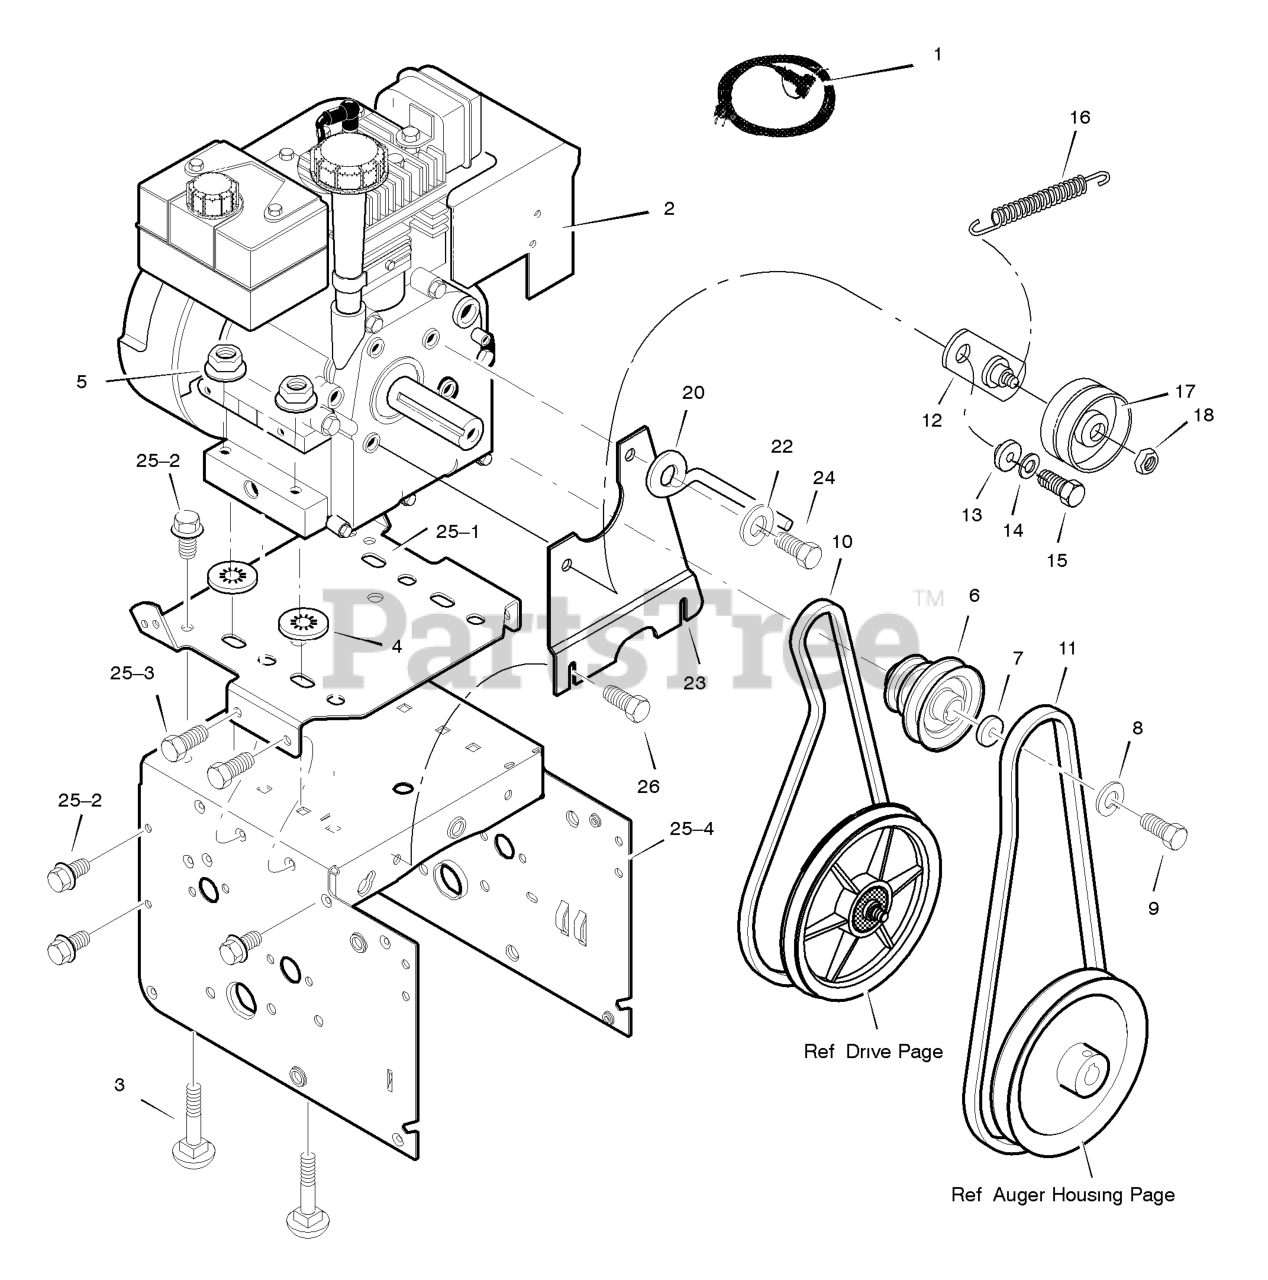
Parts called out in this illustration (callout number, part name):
1	CORD, Electric, 10FT. 110V
2	ENGINE
3	BOLT, CARRIAGE 5/16-18
4	RETAINER, PUSH
5	NUT 5/16-18
6	PULLEY, ENGINE
7	WASHER
8	WASHER
9	SCREW, 3/8-24 x 1.00
10	BELT, V
11	BELT, V
12	BRACKET ASSEMBLY, IDLER
13	BUSHING, IDLER BRACKET
14	WASHER
15	SCREW 5/16-24 X 1.00
17	PULLEY, IDLER
18	NUT, JAM 3/8-16
20	GUIDE, ROD BELT
22	WASHER, SPTLK .31X.58X.08
23	PLATE, ANTI VIBRATION
24	SCREW, 5/16-24 x 1.00
25	FRAME ASSEMBLY
25-1	PLATE, ENGINE MOUNT
25-2	SCREW 1/4-20 X .63
25-3	SCREW 5/16-18 X .50
25-4	FRAME, MOTOR BOX
